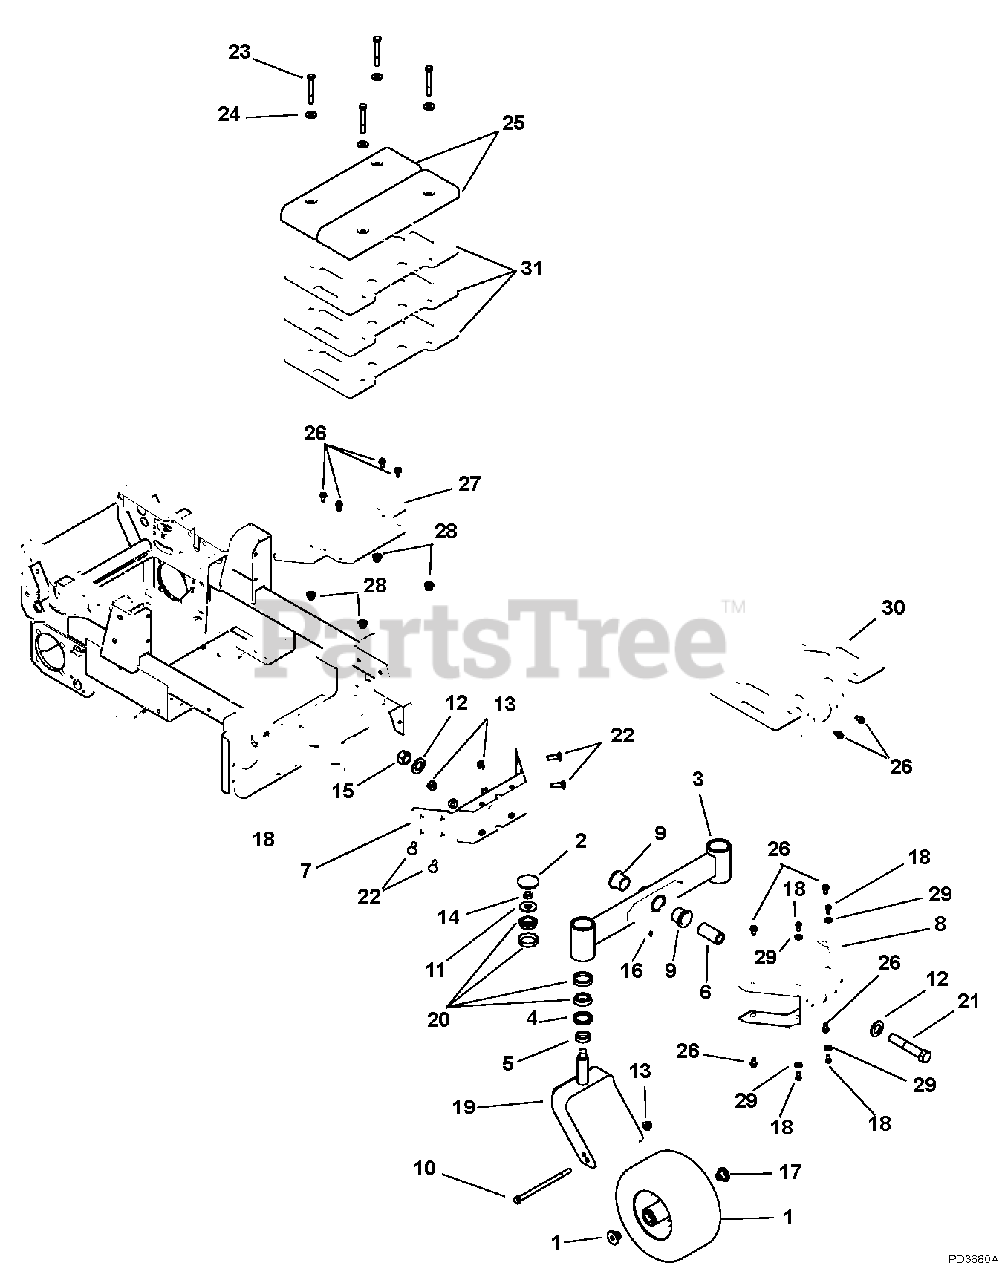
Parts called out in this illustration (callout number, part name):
1	Spacer, Front Wheel
2	Cap, Dust
3	Weldment, Rear Axle
4	Bearing Seal 1.75 x 2.332 x .312
5	Spacer, 1.258 ID x 1.75 OD x .550
6	Spacer, 1 x 1.50 x 3.16"LG
7	Weldment, Rear Axle Mounting Plate
8	Cover, Rear Axle
9	Bushing, Flange 1.514 x 1.756 x 1.688 x 2.250 Nylon
10	Bolt, Hex .50-13 x 7.50 Grade 5
11	Washer, Flat Steel .812 x 1.50 x .135
12	Washer, Flat Steel 1.062 x 2.0 x .134
13	Nut, Nyloc Flange .50-13
14	Nut, Jam Center Lock .75-16
15	Nut, Locking Nylon 1.0-8
16	Fitting, Lube .25-28 x .256
17	Tire/Wheel Assembly 13 x 6.50-6
18	Bolt, Hex .38-16 x .75 Grade 5
19	Caster, Front Fork Weldment
20	Bearing, Cup 2.328 x .465
21	Bolt, Hex 1.0-8 x 5.50 Grade 5
22	Bolt, Round Head Square Neck .50-13 x 1.50 Grade 5
23	Bolt, Hex .50-13 x 3.75 Grade 5 YWZC
24	Washer, Flat Steel .531 x 1.250 x .100
25	Weight, Cast Iron
26	Screw, Tapping .38-16 x .75 Hex Washer Head Thread Rolling
27	Bracket, Weight
28	Nut, Locking Center .50-13
29	Washer, Flat Steel .38 x .875 x .083
30	Weight Plate
31	Weight Plate
